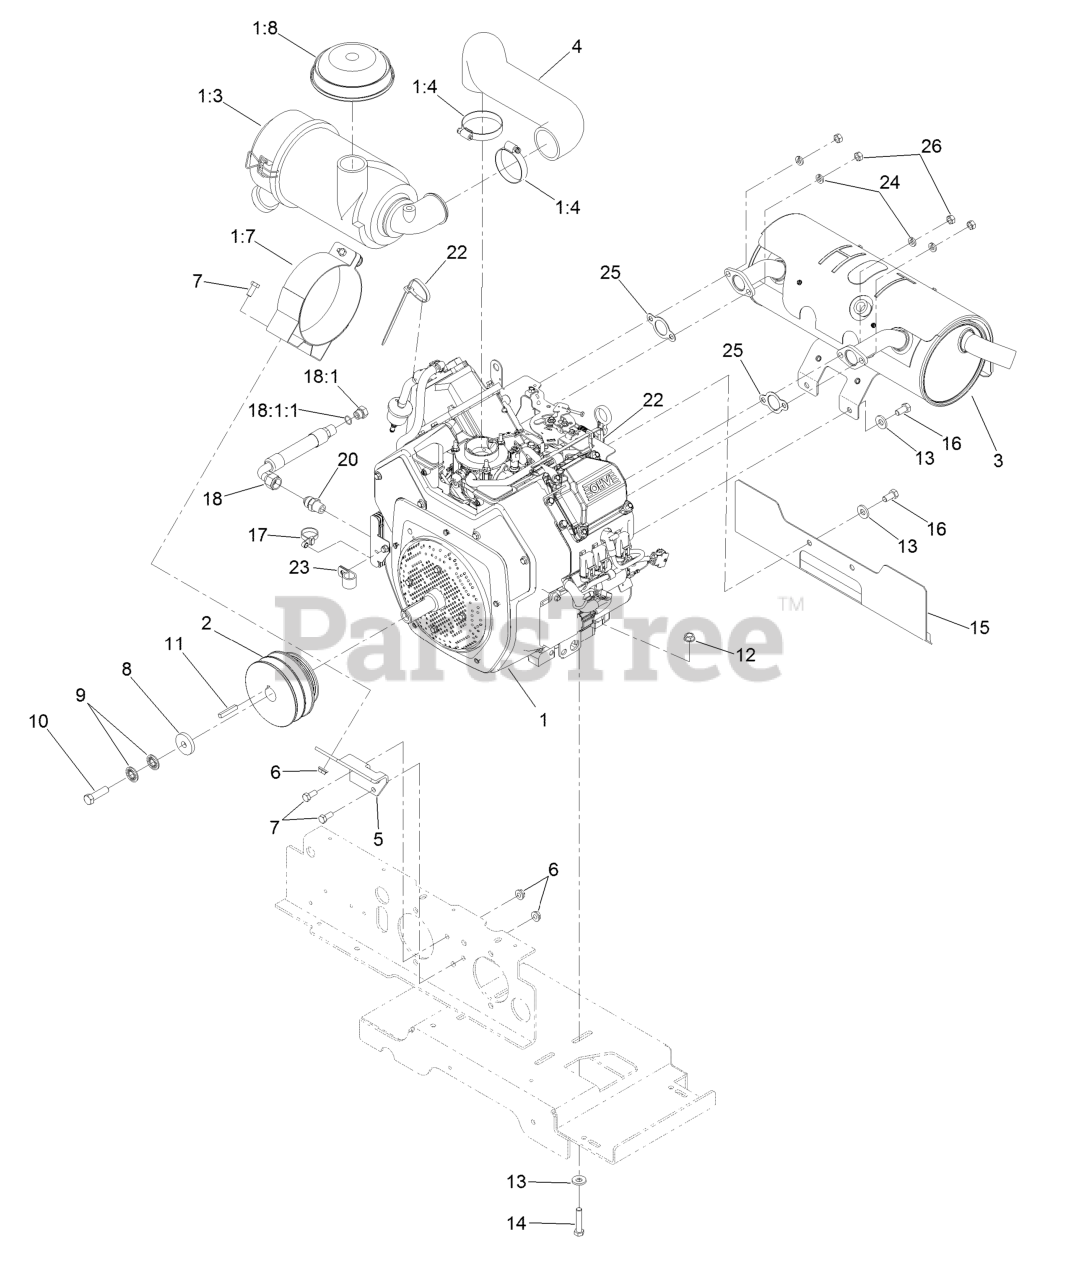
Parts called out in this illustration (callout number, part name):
1:3	Air Cleaner Canister ASM
1:4	Clamp-Hose
1:7	Bracket-Filter, Air
1:8	Hood-Cleaner, 2" Air Intake
2	Sheave-Engine
3	Muffler
4	Hose-Air Intake
5	Bracket-Filter, Air
7	Screw-HH
8	Washer-Clutch
9	Washer-Spring
10	Screw-HH
11	Key-Square
12	Nut-HHF, Whiz
13	Washer-Belleville
14	Screw-HH
15	Shield-Exhaust
16	Screw-HH
17	Tie-Cable
18	Oil Drain Hose ASM
18:1	Plug-HH
18:1:1	O-Ring
20	Fitting-Straight
22	Tie-Plastic
23	Clip-Loom
24	Washer-Lock
25	Gasket-Exhaust
26	Nut-Hex
